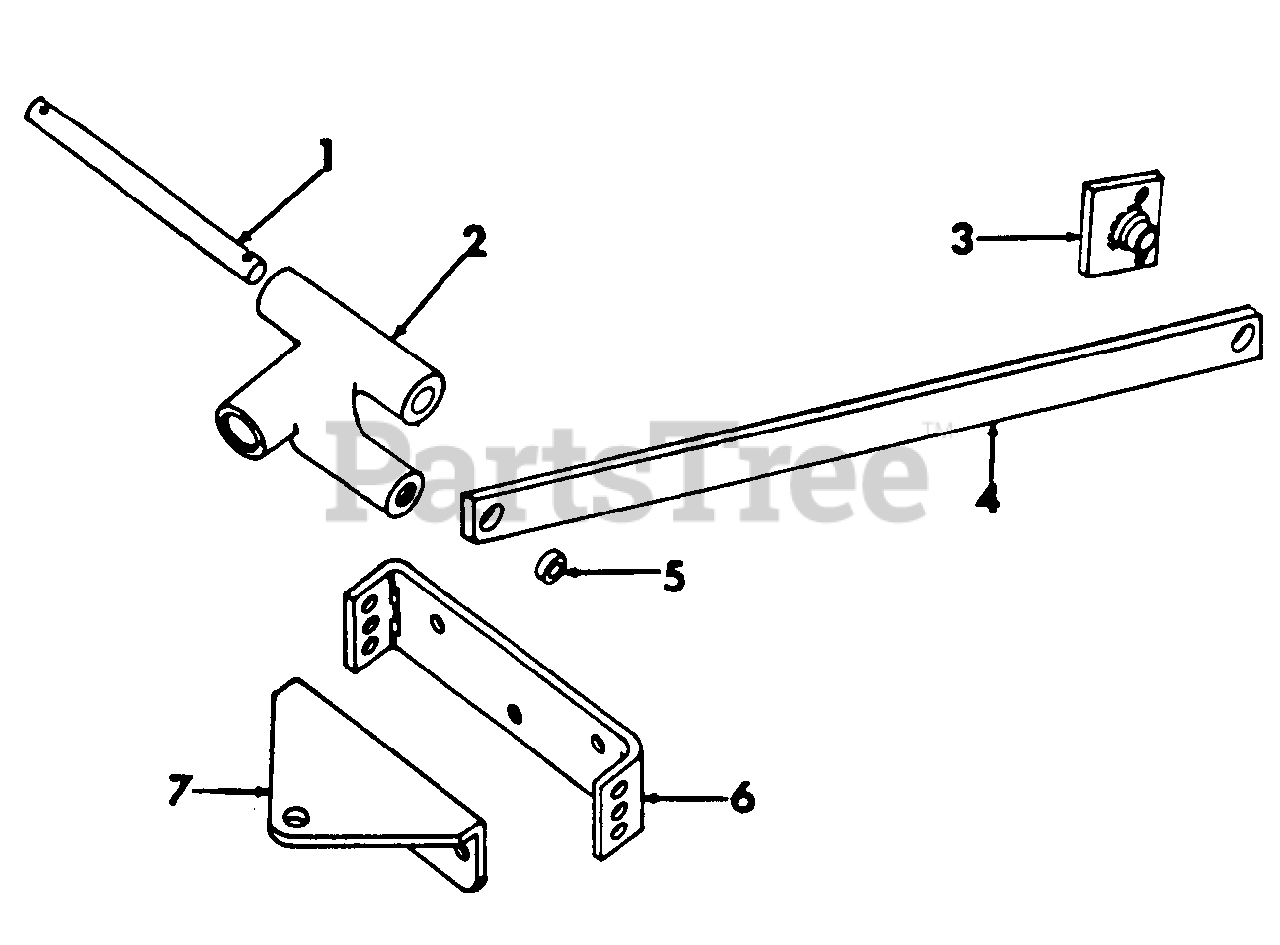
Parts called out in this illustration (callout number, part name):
1	Shaft, Lift Lever
3	Plate Assy, Lift Bar Attaching
5	Spacer, Lift Bar
7	Drawbar, Fixed
